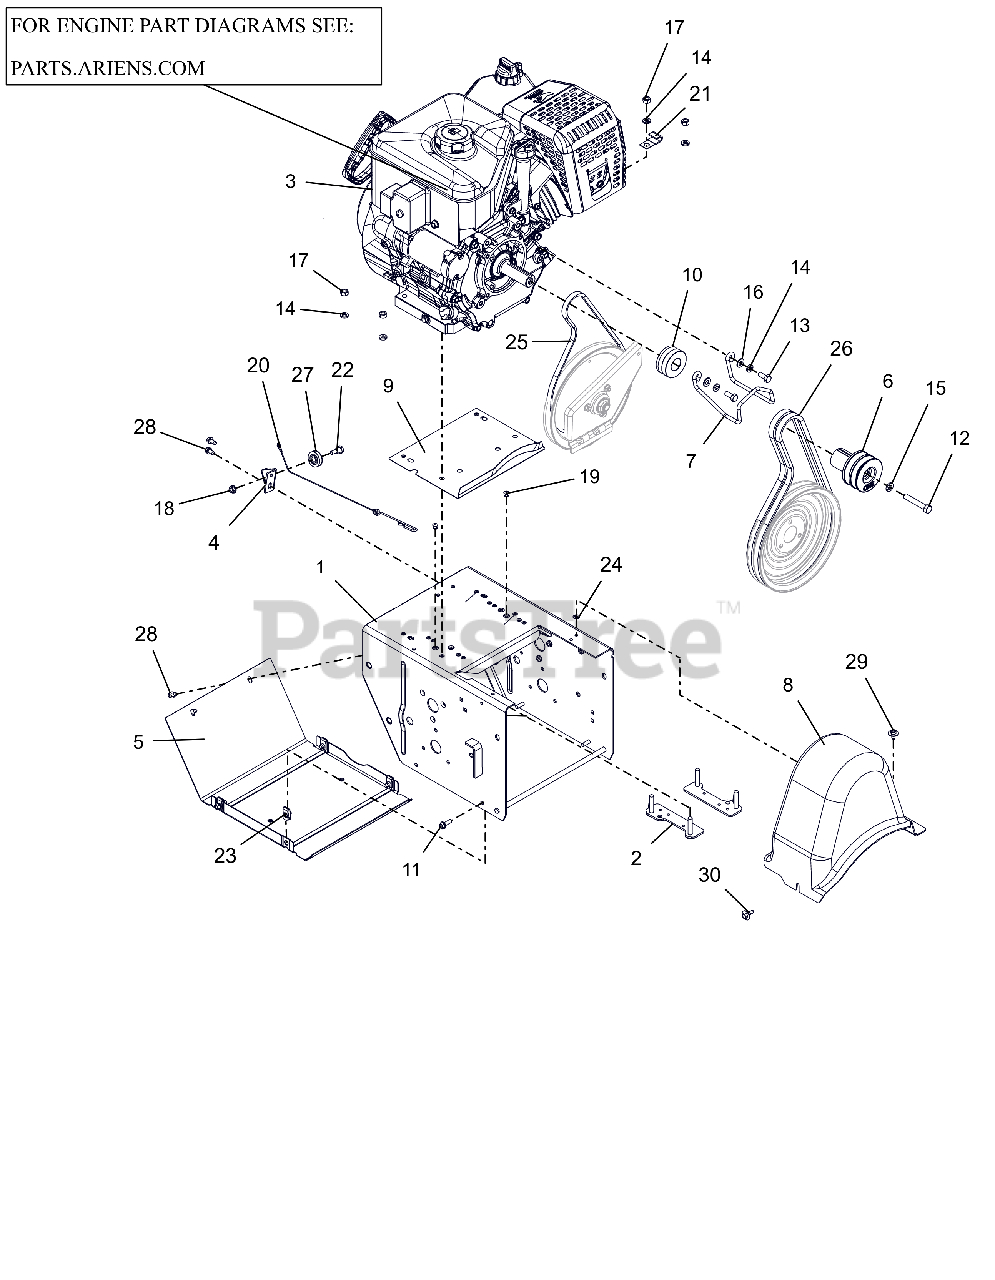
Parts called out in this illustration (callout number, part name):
1	FRAME, MAIN-DELUXE(WELDMENT)
2	STRAP, BOLT-LARGE
3	ENGINE, AX414 GEN3 120V/60W
4	BRACKET, CABLE PULLEY
5	COVER, BOTTOM
6	SHEAVE,ATTACHMENT-SHO 2 GRV
7	FINGER, BELT
8	COVER, BELT-LARGE
9	BAFFLE, WATER - LARGE BLOCK
10	SHEAVE, TRACTION (KEYLESS)
11	BLT, HWH .25-20X.75 G5 ZCC
12	BLT, HEX .38-24X2.25 G5 ZCC
13	BLT, HEX .31-24X.750 G5 ZCC
14	WSHR, LK-HVY .312X.097 ZCC
15	WSHR,LK-REG .375X.094 ZCC
16	WSHR,FLT .344X.688X.065 ZCC
17	NUT, HEX .312-18 ZCC
18	NUT-LK-TOP-FLG .250-20 GF ZCC
19	RVT, POP .1875 ZCC
20	CABLE, LOWER TRACTION,SS & PRO
21	J-CLAMP
22	BOLT, SHLDR -.375 X .375 X .25-20
23	NUT-RTNR .25-20X.56
24	NUT-PUSH .25X.50 O.D.
25	V-BELT, 3L-WRAPPED
26	V-BELT, HA-RAW EDGE (SET)
27	PULLEY, CABLE
28	SCR-TAP .25-20X.50 HWH ZCC
29	SCR, TAP .25-20X.50 LG HWH ZCC
30	SCR-TAP .25-20X.5 CAPTIVE
